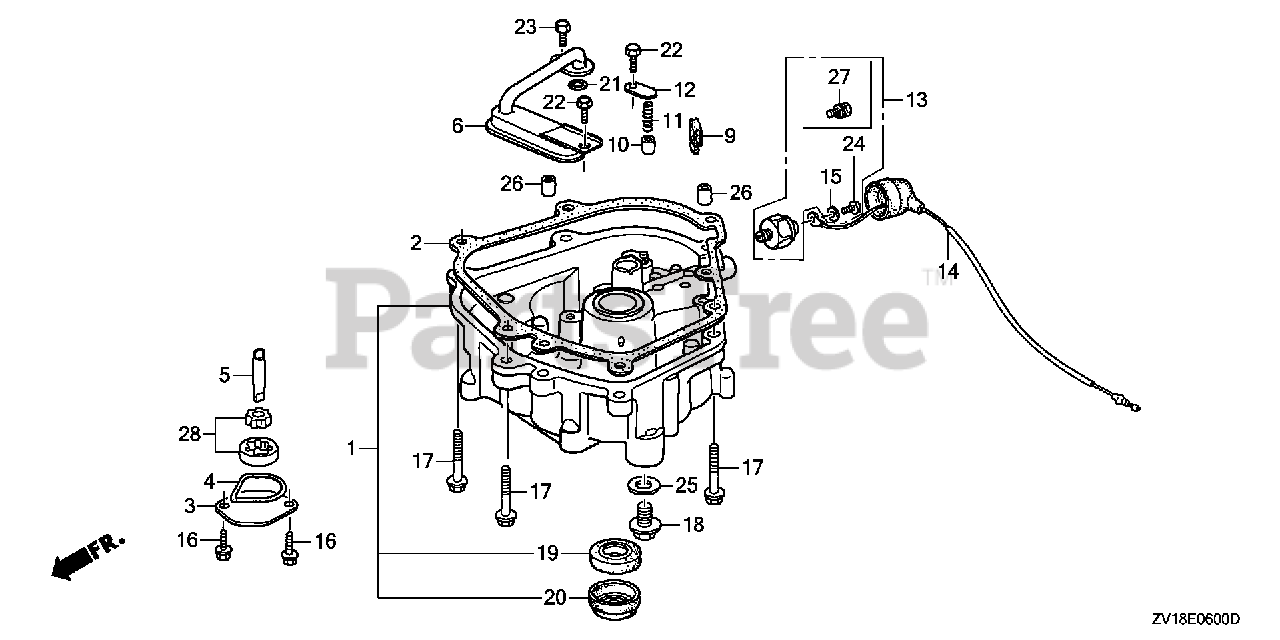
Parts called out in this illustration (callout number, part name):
1	PAN ASSY., OIL *NH8* (DARK GRAY)
2	GASKET, OIL PAN
3	COVER, OIL PUMP
4	O-RING, PUMP COVER
5	SHAFT, OIL PUMP
6	STRAINER, OIL
7	ROTOR, OIL PUMP (INNER) (YAMADA) (NOT AVAILABLE)
8	ROTOR, OIL PUMP (OUTER) (YAMADA) (NOT AVAILABLE)
9	RUBBER, OIL RETURN
10	VALVE, CHECK
11	SPRING, CHECK VALVE
12	PLATE, CHECK VALVE
13	SWITCH, OIL PRESSURE
14	WIRE, OIL PRESSURE SWITCH
15	WASHER (4MM)
16	BOLT, FLANGE (6X12) (CT200)
17	BOLT, FLANGE (8X32)
18	BOLT, DRAIN PLUG (12X15)
19	OIL SEAL (25X38X7)
19	OIL SEAL (25X38X7) (ARAI)
20	SEAL, COUPLING (25X40X14)
21	O-RING (9.6X2.6) (ARAI)
22	BOLT, HEX. (6X12)
23	BOLT-WASHER (6X14)
24	SCREW, PAN (4X6)
25	WASHER, DRAIN PLUG (12MM)
26	PIN, DOWEL (8X14)
28	ROTOR SET, OIL PUMP
